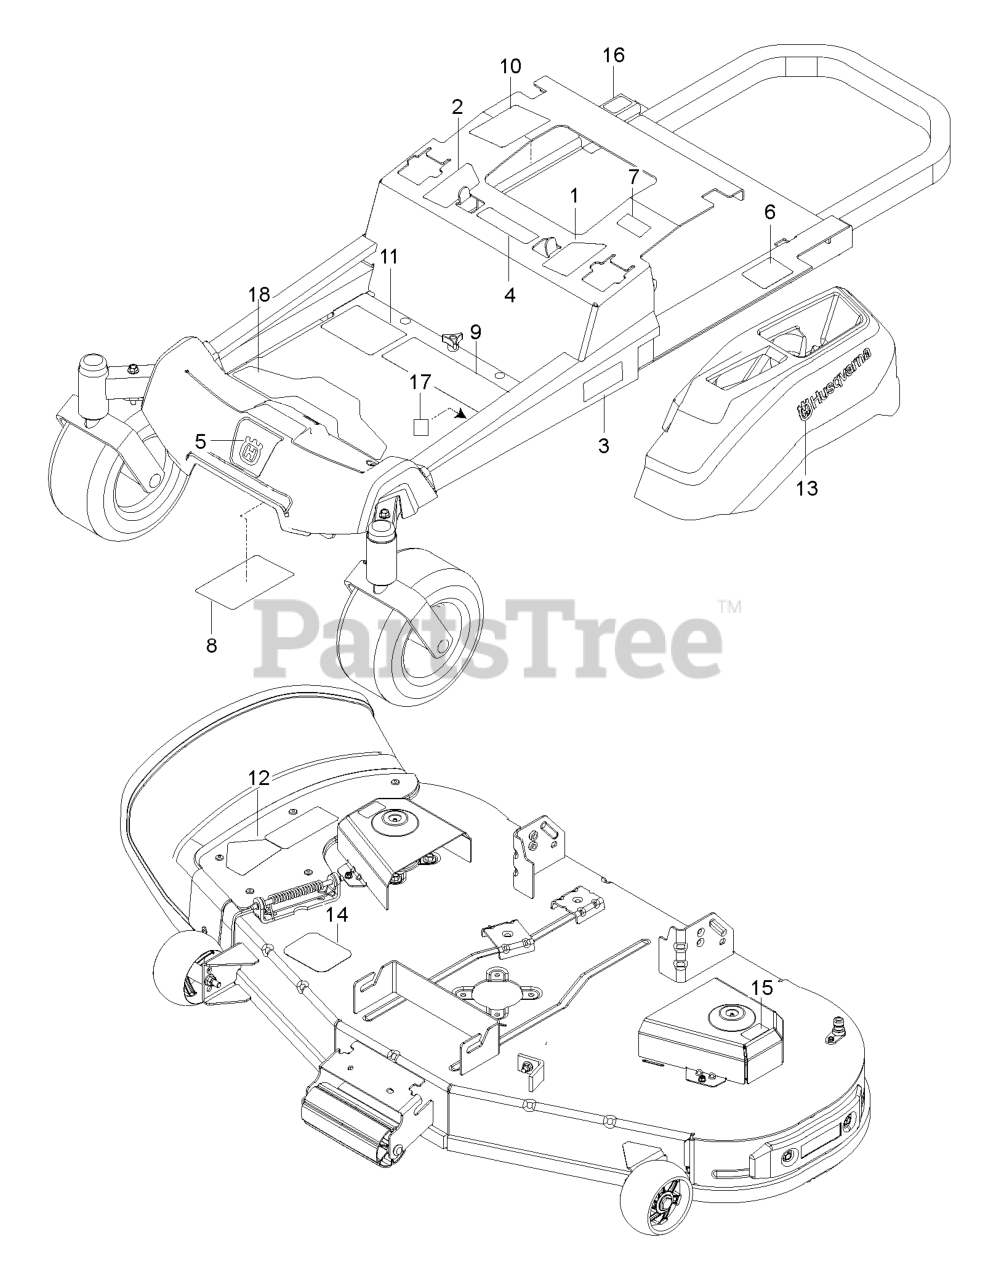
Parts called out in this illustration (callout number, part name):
1	DECAL.ZTR.RZ.THRTL/PRKBRK.V2.L
2	DECAL.ZTR.RZ.THRTL/PRKBRK.V2.R
3	DECAL.ZTR.SIDERAIL.MN.Z248F.HU
4	EURO DECAL-BATTERY WARNIN6
5	DECAL.BADGE.55MM.CROWNH.HUSQ
6	DECAL, DO NOT TOW
7	DECAL, EXITING MOWER
8	DECAL, SERVICE
9	DECAL.ZTR.WARNING.SMARTIGNITIN
10	DECAL.WARNING.CUST.RESP.E85.
11	DECAL.ZTR.STARTINSTRCT.CHOKE15
12	DECAL.TRACT/ZTR.DECKWARN.HUSQ
13	DECAL.HUSQVARNA.210MM
14	DECAL, BELT ROUTING
15	DECAL.DECK.CLEARCUT.NOSTEP
16	DECAL CERTIFICATION DECAL EMCC
17	DECAL.80.DBA.AUSTRALIA
18	PAD.RZ.FOOTREST.PLATE
